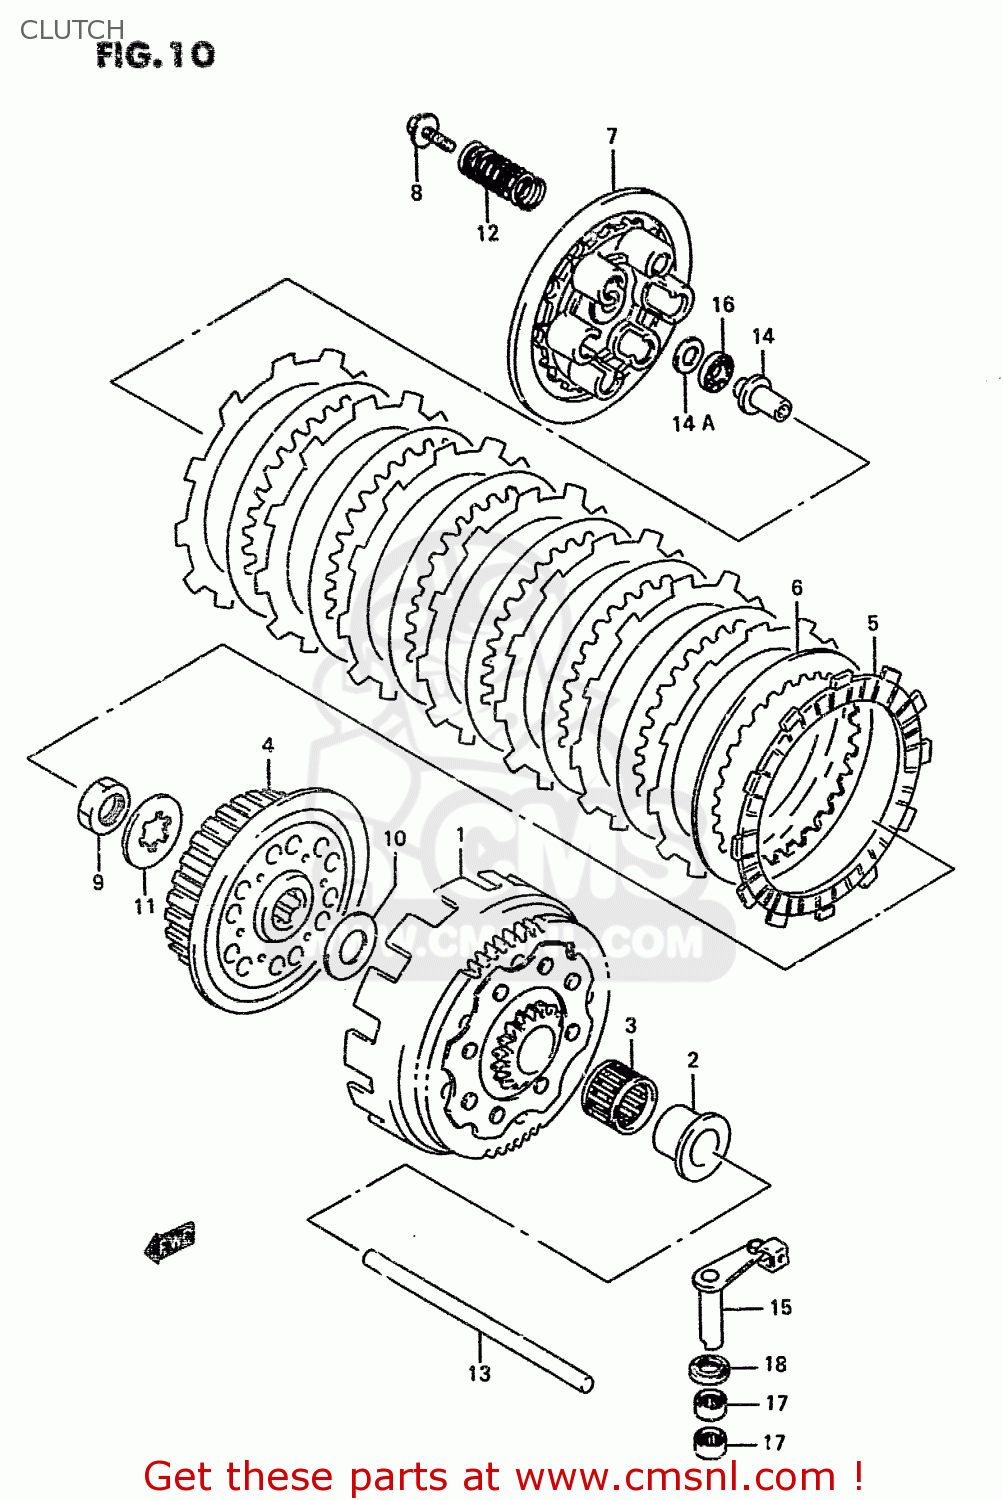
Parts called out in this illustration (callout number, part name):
1	GEAR ASSEMBLY,PRIMARY DRIVE
2	SPACER,PRIMARY DRIVEN
3	BEARING(29X34X27)
4	HUB,CLUTCH SLEEVE
5	PLATE,CLUTCH DRIVE
6	PLATE,CLUTCH DRIVEN
7	DISC,CLUTCH PRESSURE
8	BOLT(5X25)
9	NUT
10	WASHER(22X38X2)
11	WASHER,LOCK
12	SPRING
13	ROD,CLUTCH PUSH
14	PIECE,CLUTCH PUSH
14A	SHIM(10X20X0.5)
15	CAMSHAFT COMP,CLUTCH RELEASE
16	BEARING(10X22X2.8)
17	BEARING(12X16X10)
18	SEAL,OIL(12X19X5)
